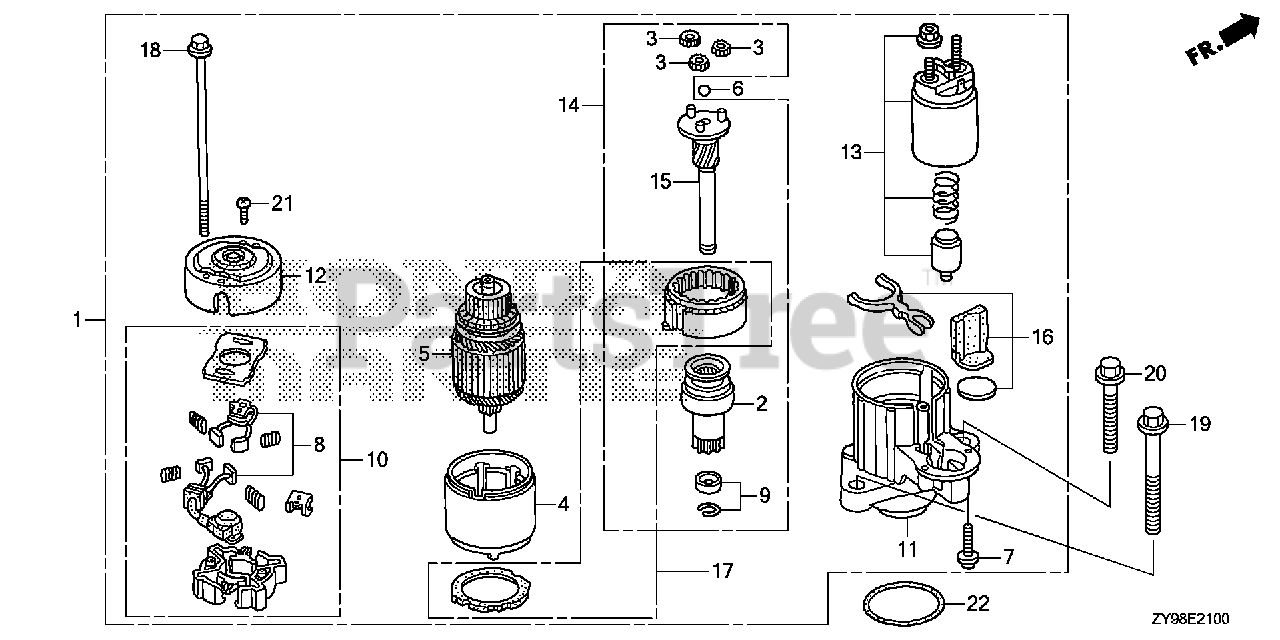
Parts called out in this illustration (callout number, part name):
1	STARTER MOTOR ASSY.
2	CLUTCH, OVERRUNNING
3	GEAR ASSY., PLANETARY
6	BALL, STEEL
7	SCREW, PAN (6X22)
9	STOPPER SET, SLEEVE
10	HOLDER, BRUSH
11	BRACKET, FR.
12	BRACKET, RR.
13	SWITCH ASSY., MAGNET
14	SHAFT ASSY., CLUTCH
15	SHAFT ASSY., GEAR
17	GEAR ASSY. (INNER)
18	BOLT A, THROUGH
19	BOLT, FLANGE (10X75)
20	BOLT, FLANGE (10X35)
21	SCREW, PAN (5X8)
22	O-RING (59.4X3.1)
